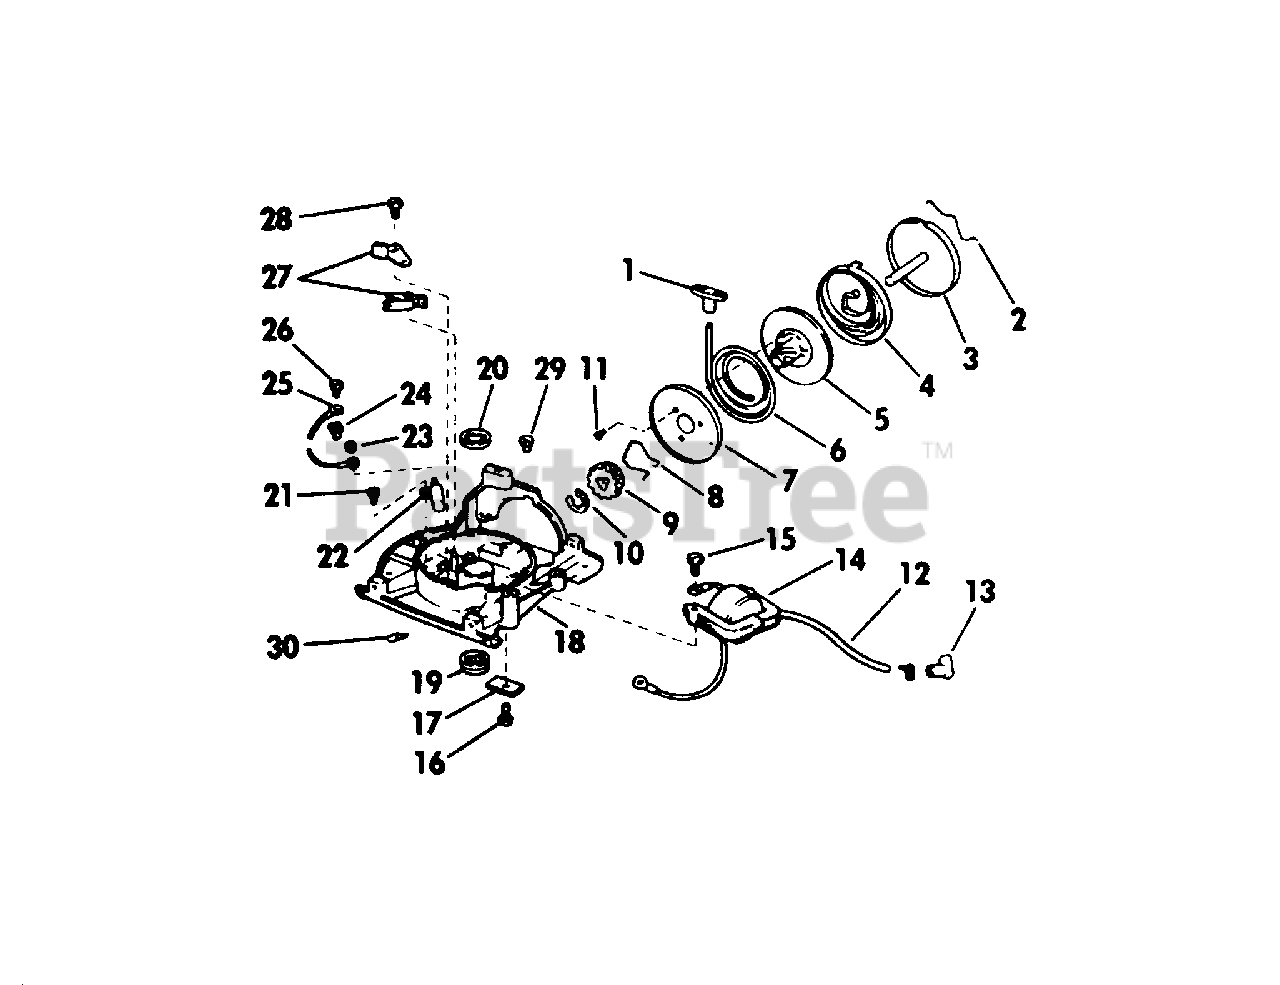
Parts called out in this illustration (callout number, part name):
1	Handle-Starter
2	Spring-Starter Rope Retainer
3	Spring-Cup-Pin Assy.
4	Spring-Starter
5	Pulley-Starter
6	Rope-Starter
7	Plate-Starter Pulley
8	Spring-Starter Pinion
9	Pinion-Starter
10	Retainer-Push-On
11	Screw-Threaded Cutting Starter
12	High Tension Lead Assy.
13	Cover & Terminal Assy.
14	Coil & Lamination Assy.
15	Scr.-Lamination Mtg.
16	Scr.-Starter Attach.
17	Clamp-Starter Pin
18	Arm. Pl., Brg. & Oil Seal Assy.
19	Brg. & Seal Assy.
20	Oil Seal
21	Scr.-Cond. Mtg.
22	Cond. & Nut Assy.
24	Grommet-Nylon
25	Terminal & Lead Assy.
26	Scr.-Shut-Off Sw.
27	Brkr. Base & Arm Assy.
28	Scr.-Breaker Base
29	Grommet
